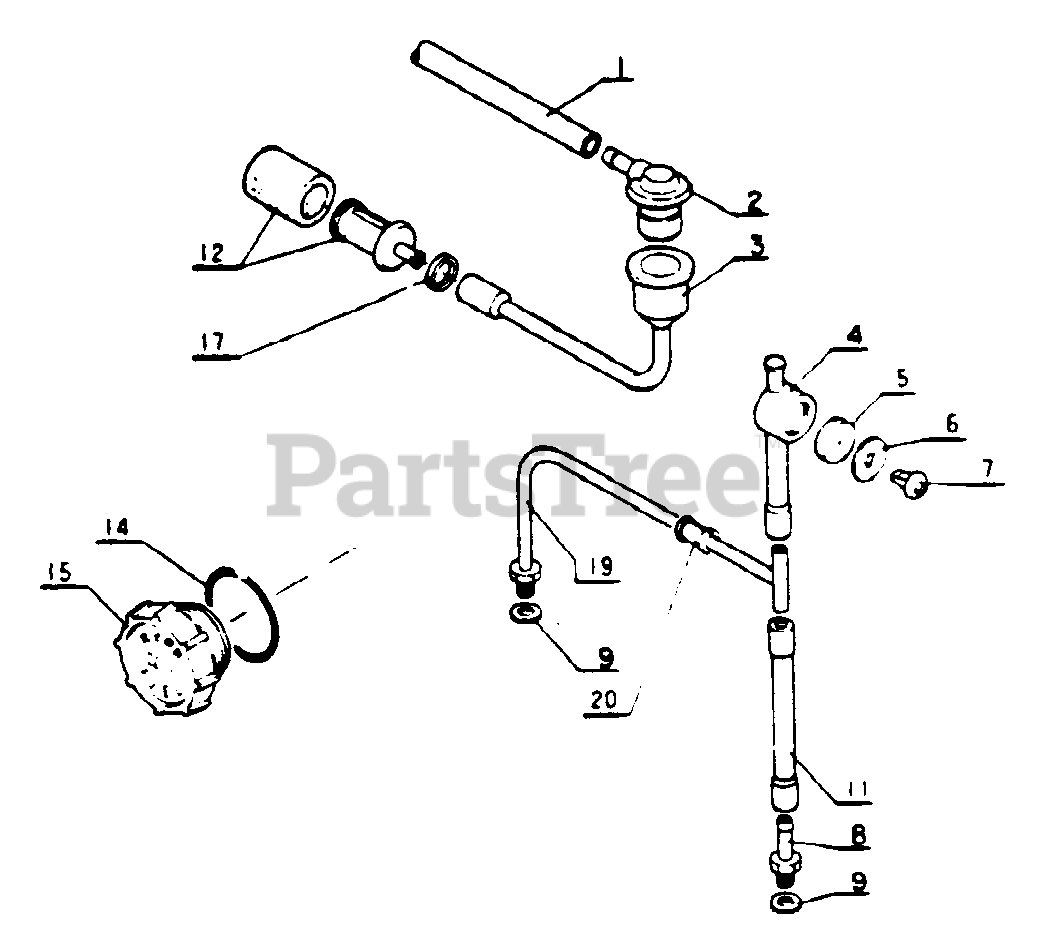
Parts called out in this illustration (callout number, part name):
1	PIPE, FUEL - OUTER
2	CONNECTOR, PIPE
3	PIPE, FUEL
4	AIR PIPE
5	FILTER, AIR VALVE
6	HOLDER, VENT
7	VALVE, CHECK
8	FITTING, GREASE
11	CONNECTOR
12	FILTER, FUEL
14	O-RING
15	CAP
17	RETAINER, PIPE
